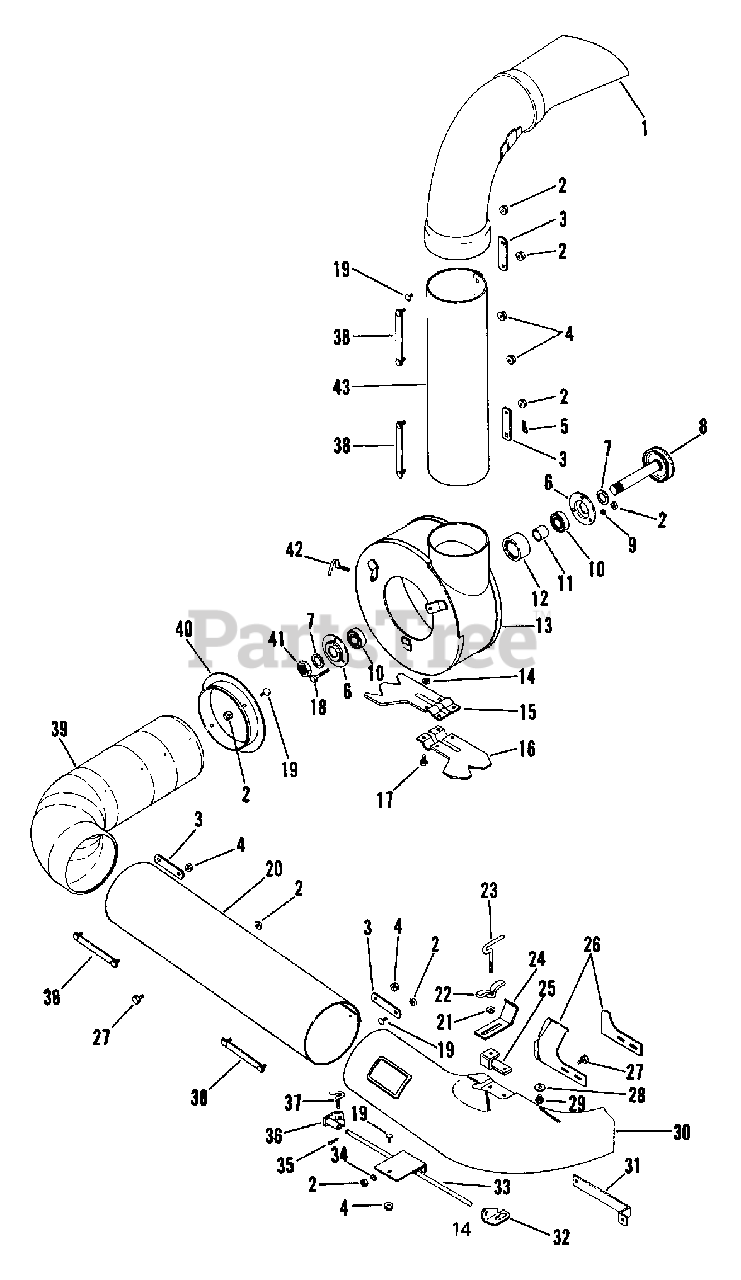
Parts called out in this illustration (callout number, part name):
1	UPPER ELBOW
2	NUT-LK-CTR .250-20 PL
4	NUT-LK-FLG .250-20 PL
5	PIN-HAIR INT .08X.18X1.18
6	BEARING FLANGE
7	WSHR-FL-STL 1.015X1.500X.125
8	SPINDLE WELDMENT
9	WSHR-FL-STL .268X.562X.046 PL
10	BRG-BALL 1.0X2.0X.56
11	SPACER 1.010X1.250X.924
12	HOUSING
13	FAN HOUSING W/DECAL
14	NUT-LK .312-18 GR A PL
15	FAN BLADE
16	FAN BLADE
17	BLT-HEX .31-18X.63 PL GR 2
18	BLT-HEX .25-20X2.00 PL GR5
19	BLT-RDHDSQNK .25-20X.50 SHT PL
21	WSHR-FL-STL .38X.875X.083 PL
22	WING NUT, .312-18
23	CLAMP SCREW
24	DEFLECTOR STOP
25	COLLECTOR BOOT CLAMP
25	VAC PLATE
27	BLT-HEX .25-20X.63 PL GR2
28	WSHR-FL-STL .281X1.250X.048PL
29	BLT-HEX .25-20X.38 PL GR2
31	BRACKET - STOP
32	BOOT CLIP
33	BOOT BRACE
34	WSHR-FL-STL .250X.562X.049 PL
35	PIN-COTR .09X.75 PL
36	BOOT CLAMP
37	CLAMP SCREW
39	ADAPTER
40	HOSE ADAPTER
41	NUT-LK-JAM 1.0-14 PL
42	CLAMP SCREW
43	TUBE, UPPER
